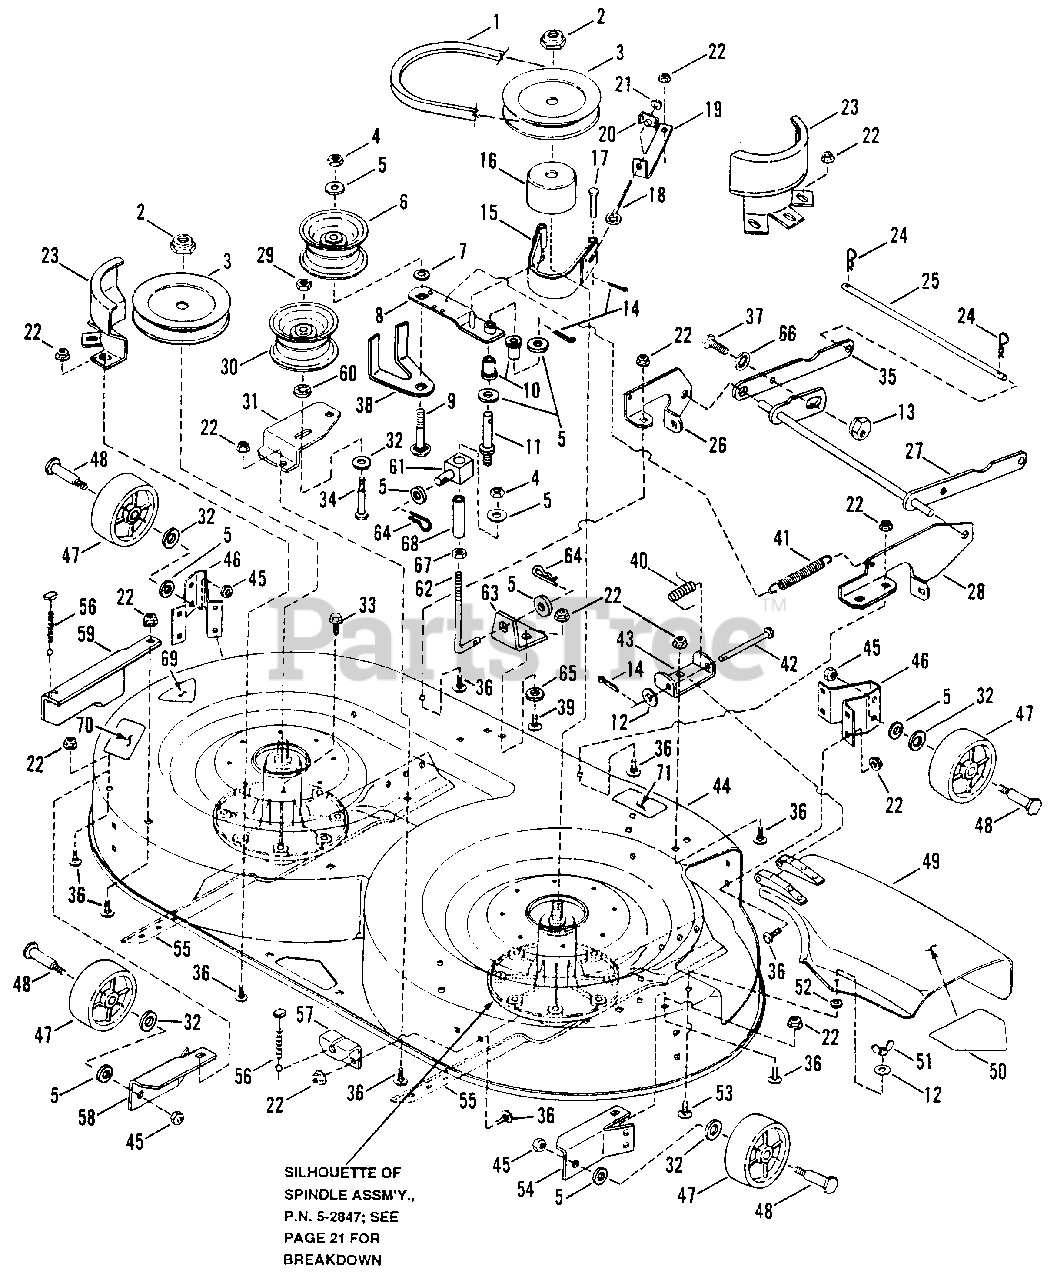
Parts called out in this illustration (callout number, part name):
1	BELT, Drive, 38" Cutting Deck
2	NUT, 5/8-18 Hex Nyloc
3	PULLEY, Spindle
4	NUT, 3/8-16 Hex Nyloc
5	WASHER, 3/8" Flat
6	PULLEY, Idler
7	RETAINER, 3/8 Bolt
8	ARM, Idler Pulley
9	BOLT, 3/8-16 x 2 3/4" Short Neck Carriage, Grade 5
10	BUSHING, Flange
11	STUD, Idler
12	WASHER, Flat
13	ECCENTRIC, Leveling
14	COTTER-PIN, 3/32 x 3/4"
15	ASSEMBLY, Brake Band
16	DRUM, Brake
17	PIN, 1/4 x 1 5/8" Clevis
18	BOLT, 1/4-20 Eye
19	ANCHOR, Blade Brake
20	NUT, 1/4-20 "T" Lock
21	NUT, 1/4-20 Hex
22	NUT, 5/16-18 Hex Flange Lock
23	GUARD, Belt
24	PIN, Hair
25	PIN, Deck Hanger
26	BRACKET, Front Lift Arm (Left Side)
27	LIFT, Front Arm
28	BRACKET, Front Lift Arm (Right Side)
29	NUT, 1/2-13 Hex Nyloc
30	PULLEY, Idler
31	BRACKET, Idler
32	WASHER, 1/2 Flat
33	SCREW, 3/8-16 x 3/4" Self-Tapping
34	BOLT, 1/2-13 x 3" Hex Head Cap
35	ARM, Front Lift
36	BOLT, 5/16-18 x 1/2" Short Neck Carriage
37	BOLT, 3/8-24 x 3/4" Hex Head
38	GUIDE, Belt
39	BOLT, 5/16-18 x 3/4" Short Neck Carriage
40	SPRING, Chute Deflector Hinge
41	SPRING, Blade Brake
42	PIN, 5/16 x 3 3/16" Clevis
43	HINGE, Chute Deflector
44	DECK, 38" Cutting
45	NUT, 3/8-24 Hex Lock
46	BRACKET, Gage Wheel, Front
47	WHEEL, Gage
48	BOLT, 3/8-24 Shoulder
49	ASSEMBLY, Chute Deflector
50	DECAL, DANGER
51	NUT, 5/16-18 Wing
52	RETAINER, 5/16 Bolt
53	BOLT, 5/16-18 x 3/4" Short Neck Carriage, Grade 2
54	BRACKET, Wheel, Right Side
55	BLADE, 19-1/2"
56	CABLE, Rear Lift, 5.62"
57	BRACKET, Rear Deck Lift (Right Side)
58	BRACKET, Wheel (Left Side)
59	BRACKET, Rear Deck Lift (Left Side)
60	RETAINER, 1/2" Bolt
61	SWIVEL, Lift
62	BOLT, "J"
63	BRACKET, Angle (Front)
64	PIN, Hair
65	WASHER, 7/16 Flat
66	WASHER, 3/8 Internal Tooth Lock
67	NUT, 3/8-16 Hex
68	SPACER, Lift
69	DECAL - Inch
70	DECAL - CAUTION (Rotating Blades)
71	DECAL - CAUTION
